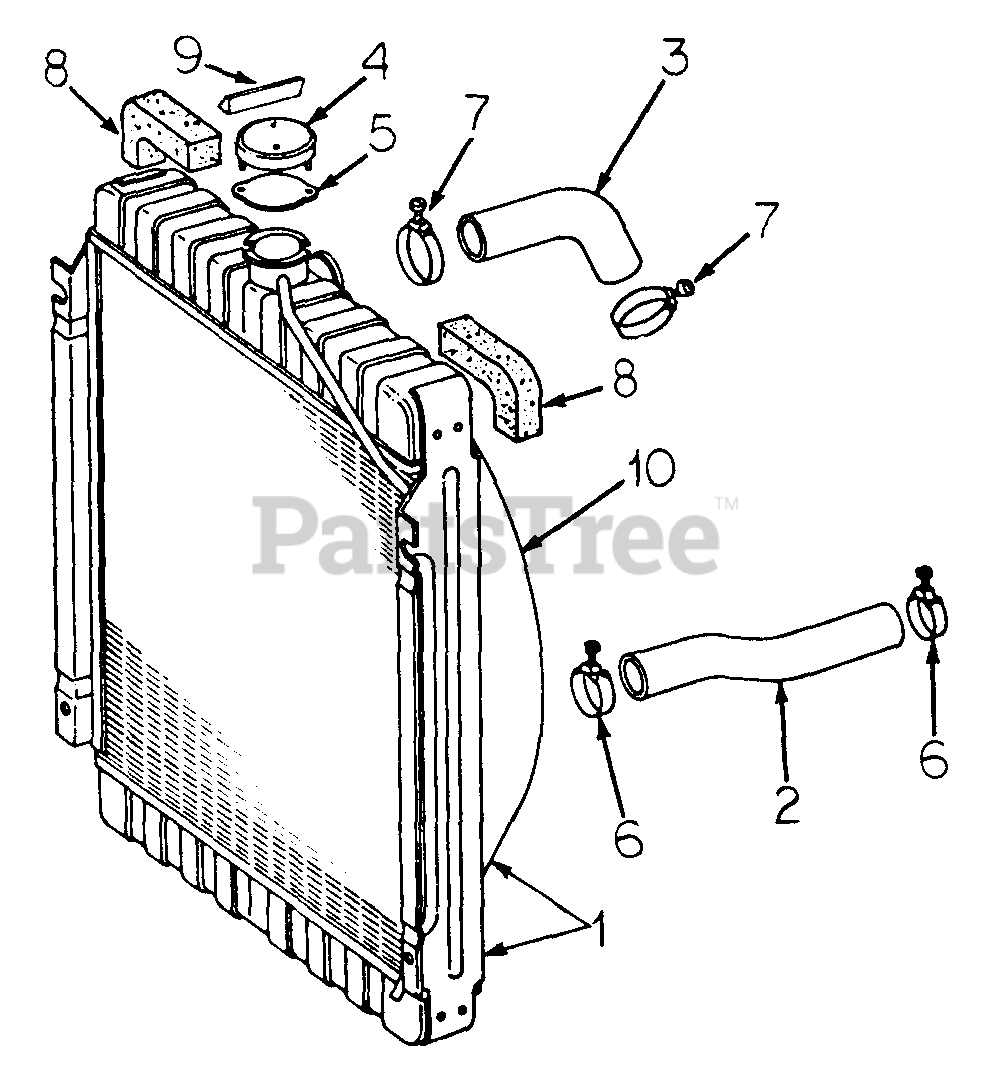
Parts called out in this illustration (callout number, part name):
1	RADIATOR ASSY
2	HOSE, RADIATOR BOTTOM
3	HOSE, RADIATOR TOP
4	CAP ASSY, RADIATOR W/PRODUCT GRAPHIC
5	CAP, RADIATOR
6	CLAMP, RADIATOR HOSE LOWER
7	CLAMP, RADIATOR HOSE TOP
8	GASKET, RADIATOR BAFFLE UPPER
9	PRODUCT GRAPHIC, RADIATOR CAP ORNAMENT
